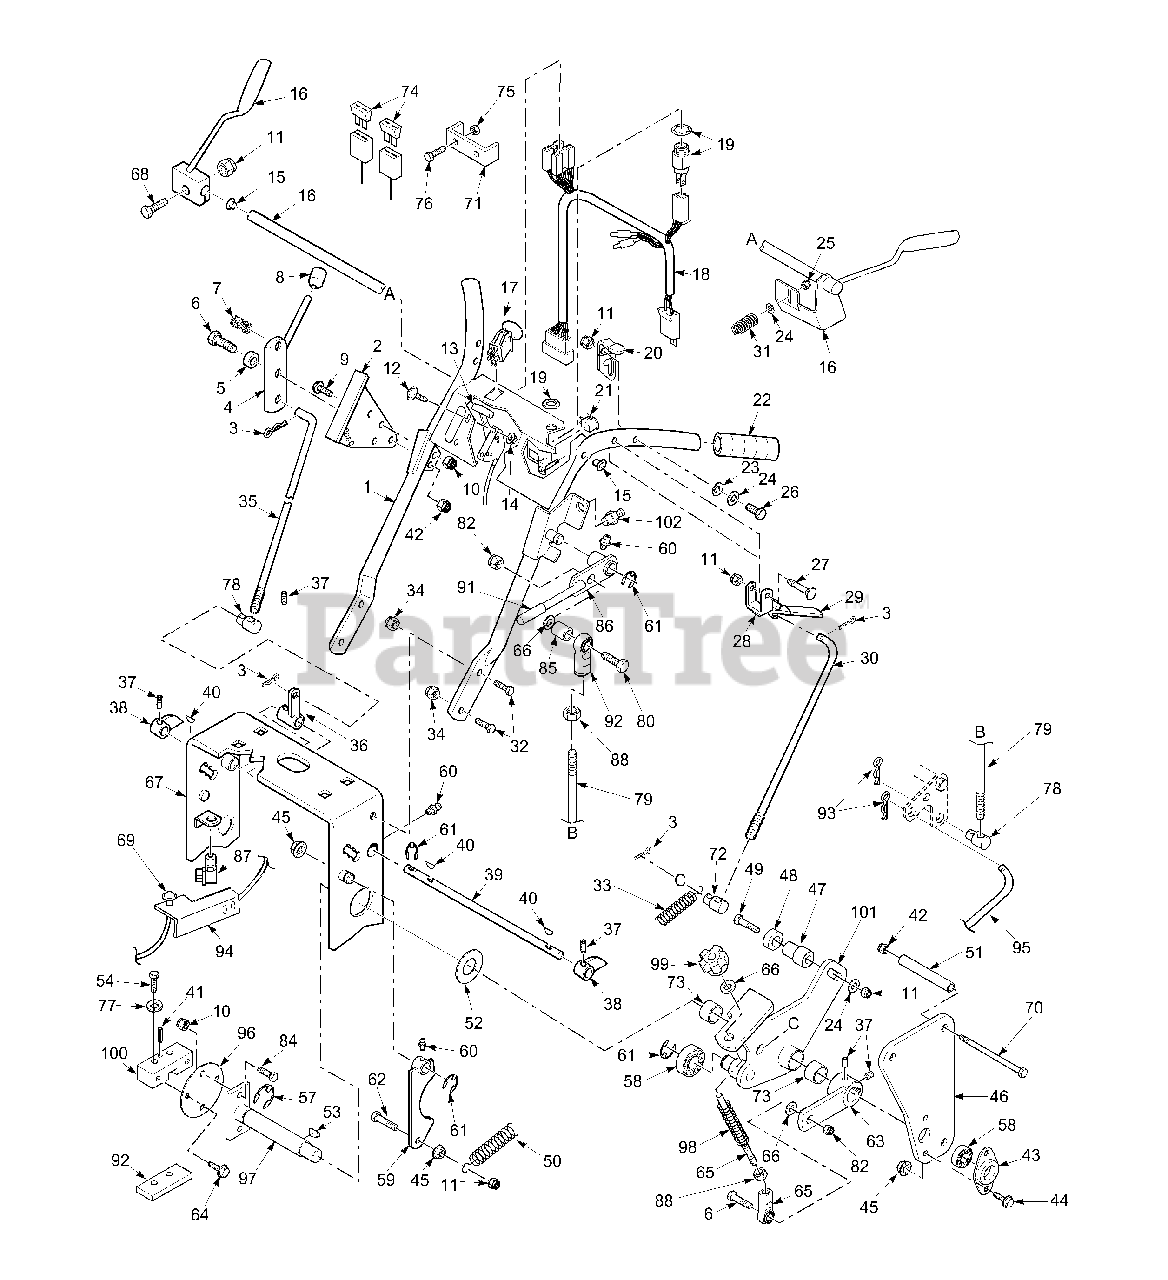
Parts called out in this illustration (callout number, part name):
1	Upper Handle Wlmt. W/Decals
2	Quadrant, Speed Control
3	Hairpin, .094 x 1.19
4	Lever, Speed Adjustment
5	Bushing, Speed Adjustment Lever
6	Hex Head Bolt, 3/8-16 x 1.5"
7	Ball Plunger
8	Knob, Speed Adjustment
9	Capscrew, 1/4-20 x 3/4" FHHS
10	Nut, 1/4-20 Elastic Stop
11	Nut, 5/16-18 Elastic Stop
12	Screw, #10-32 x 1/2" PW HD
13	Throttle Control
14	Nut, #10-32 Serr. Flange
15	Bushing
16	Handle, Oper. Presence-RH
17	Switch,Elec.Clutch Eng.
18	Wire Harness, Electric Start
19	Key Switch, Electric Srt
20	Neutral Latch-RH
21	Switch, Neutral Interlock
22	Grip
23	Washer, Curved Spring
24	Flat
25	Nut, 5/16-18 Elastic Stop
26	Hex Head Bolt, 5/16-18 x 2"
27	Hex Hd. Bolt, 5/16-18 x 2.5"
28	Lever, Steering Control
29	Grip, Steering Control
30	Rod, Steering Control
31	Spring, Handle Return
32	Capscr., 3/8-16 x 1" Ser. Flange
33	Spring
34	Nut, 3/8-16 Serr. Flange
35	Rod Speed Control
36	Bellcrank, Speed Control
37	Setscrew, 1/4-28 x .25"
38	Cam, Speed Control
39	Jackshaft, Speed Control
40	Key, 1/8 x 1/2" Woodruff
41	Roll Pin, 3/16-.75
42	Nut, Elastic Stop 3/8-16
43	Flange, Bearing
44	Capscrew, 5/16-18 x 1" Serr. Flg.
45	Nut, 5/16-18 Serrated Flange
46	Plate, Side
47	Support, Neutral Support
48	Bearing, Speed Ctrl. Bellcrank
49	Hex Head Bolt, 5/16-18 x 1-3/4"
50	Spring, Return
51	Spacer, Side Plate
52	Flat Wshr., 3/4-.766 x 1.25 x .035
53	Key, Woodruff, 3/16 x .75"
54	Bolt, Hex Head, 1/4-20 x 1.25
55	HH Bolt,5/16-18 x .75"
56	Lock Washer, 5/16
57	Clip, Retaining .750 diameter
58	Bearing, Ball Neutral Return
59	Cam, Neutral
60	Grease Fitting, 1/4-28 UNF
61	Retaining Ring, 5/8 Ext. "E"
62	Hex Head Bolt, 5/16-18 x 1"
63	Lever, Speed Control
64	Bolt, Serr. Flange 1/4-20 x.75"
65	Linkage Assembly
66	Flat Wshr., 15/16 x .3906 x 12 ga
67	Deck, Engine 20" Wide
68	Hex Head Bolt, 5/16-18 x 1.25"
69	Choke Control
70	Bolt, Hex Head 3/8-16 x 4.25"
71	Fuse Holder
72	Swivel Joint, Steering Rod
73	Bushing
74	Blade Fuse, 20A
75	Nut, #10-32 Elastic Stop
76	Screw, #10-32 x 1.5" Phillips
77	Lockwasher, 1/4"
78	Swivel Joint
79	Rod, Brake Lever
80	Hex Hd. Bolt, 3/8-16 x 1.75"
81	Soc. Hd. Capscrew, #8-32 x .5"
82	Nut, 3/8-16 Elastic Stop
83	Washer #8-.170 x .375 x .032
84	Bolt, 1/4-20 x .75"
85	Spacer
86	Parking Brake Lever with Grip
87	Switch, Safety
88	Nut, 3/8-24
89	Bushing, Bearing Retainer
90	Bearing, Neutral Lock
91	Grip, Parking Brake
92	Plate, Threaded
93	Hairpin, .094 x 1.62"
94	Bracket, Choke Mtg.
95	Rod, Lower Brake
96	Plate, Coupler
97	Shaft, Pump Control
98	Spring
99	Knob, Tracking Adjustment
100	Block, Pump Control
101	Control, LH
102	Switch, Parking Brake
